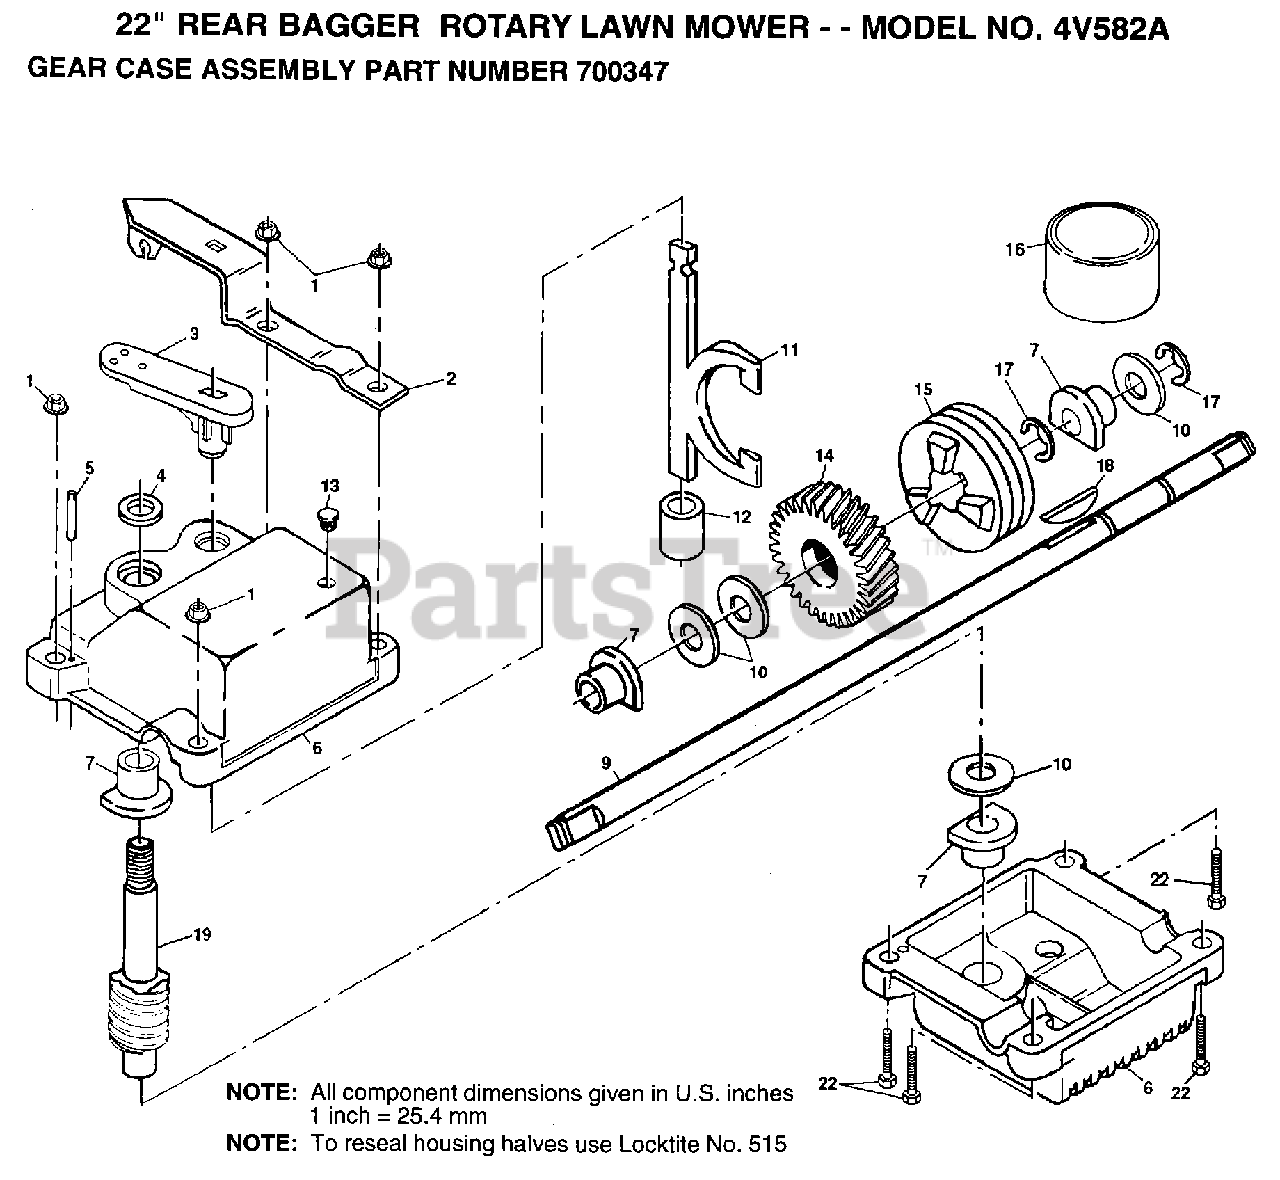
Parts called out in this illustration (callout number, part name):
1	NUT
3	SHIFTER
4	SEAL
5	DRIVE LOK PIN
6	GEARCASE KIT
7	BEARING
9	SHAFT.DRIVE
10	THRUST WASHER
11	CLUTCH YOKE
12	BUSHING.GEAR BOX
13	PLUG PM
14	GEAR.HELICAL
15	CLUTCH JAW
17	RING T
18	HI PRO KEY
19	SHAFT.WORM
